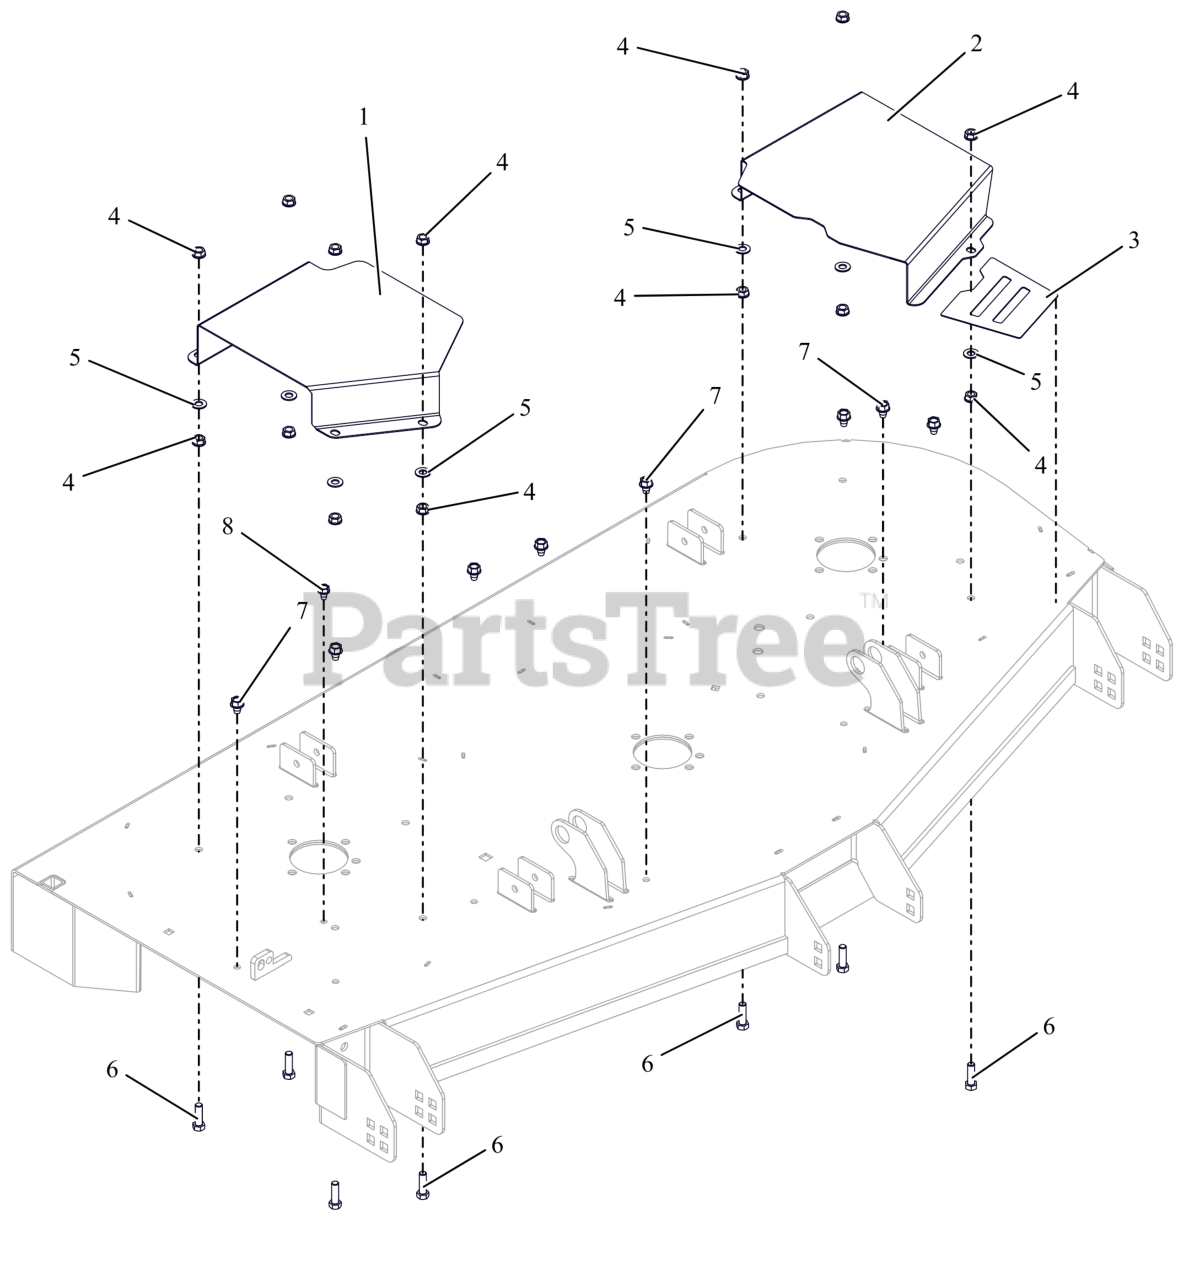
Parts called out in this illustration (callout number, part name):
1	COVER, BELT 52" & 60" RIGHT
2	COVER- BELT 60" LEFT
3	GRIP TAPE 52-60 BELT COVER
4	NUT, SPNLK-FLG .38-16 G5 ZCC
5	WSHR,FLT .406X.812X.065 ZCC
6	BLT, HEX .38-16X1.25 G5 ZCC
7	SCR,TAP .375-16X.50 HWH TR ZCC
8	SCR,TAP .312-18X.50 HWH TR ZCC
